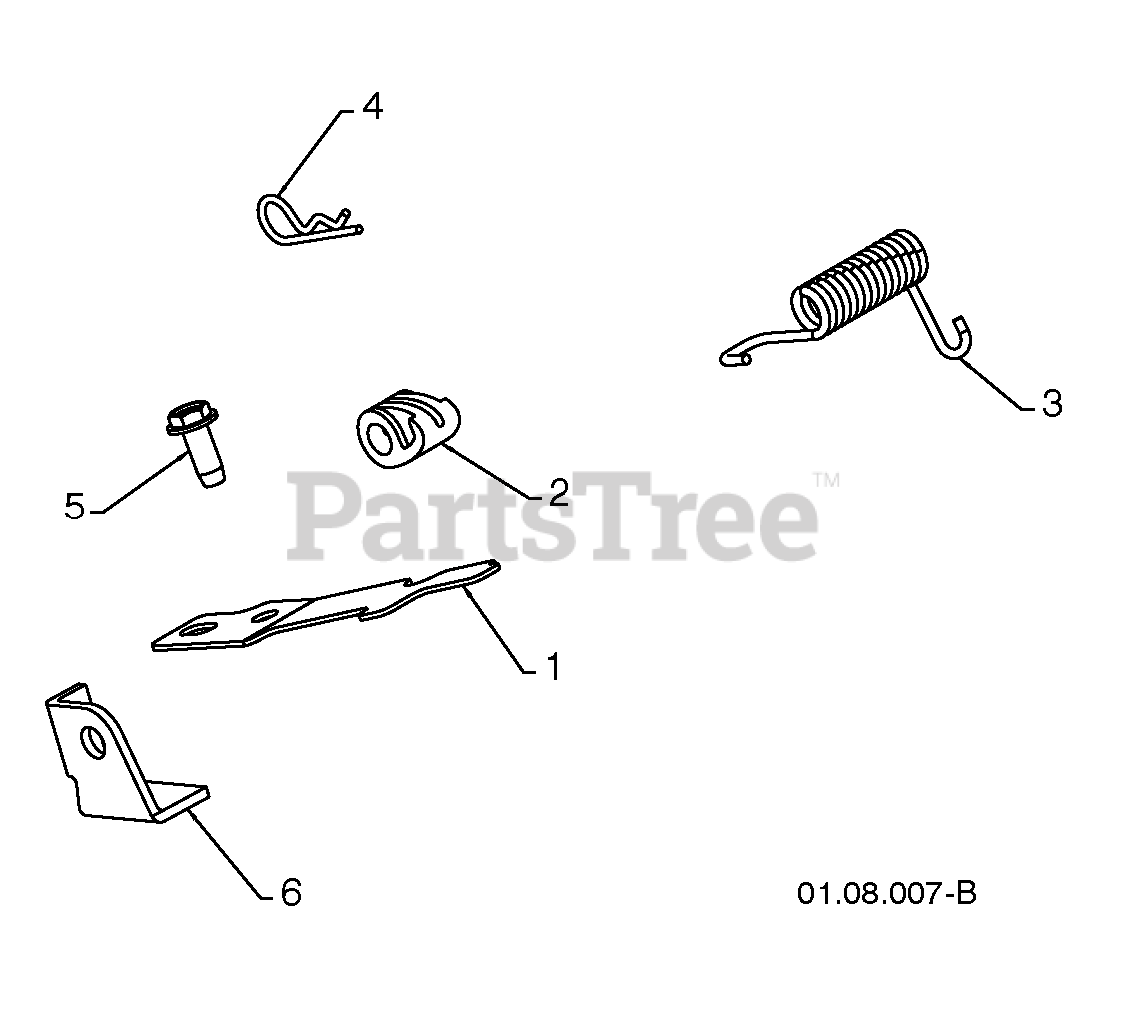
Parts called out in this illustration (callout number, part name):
1	RP SPRING.INTERLOCK
2	CAM.INTERLOCK.RELEASE
3	RP SPRING, TORSION
4	SPRING RETAINER
5	SCREW 14-20 X 5/8
6	STOP.INTERTLOCK.SPRING.
